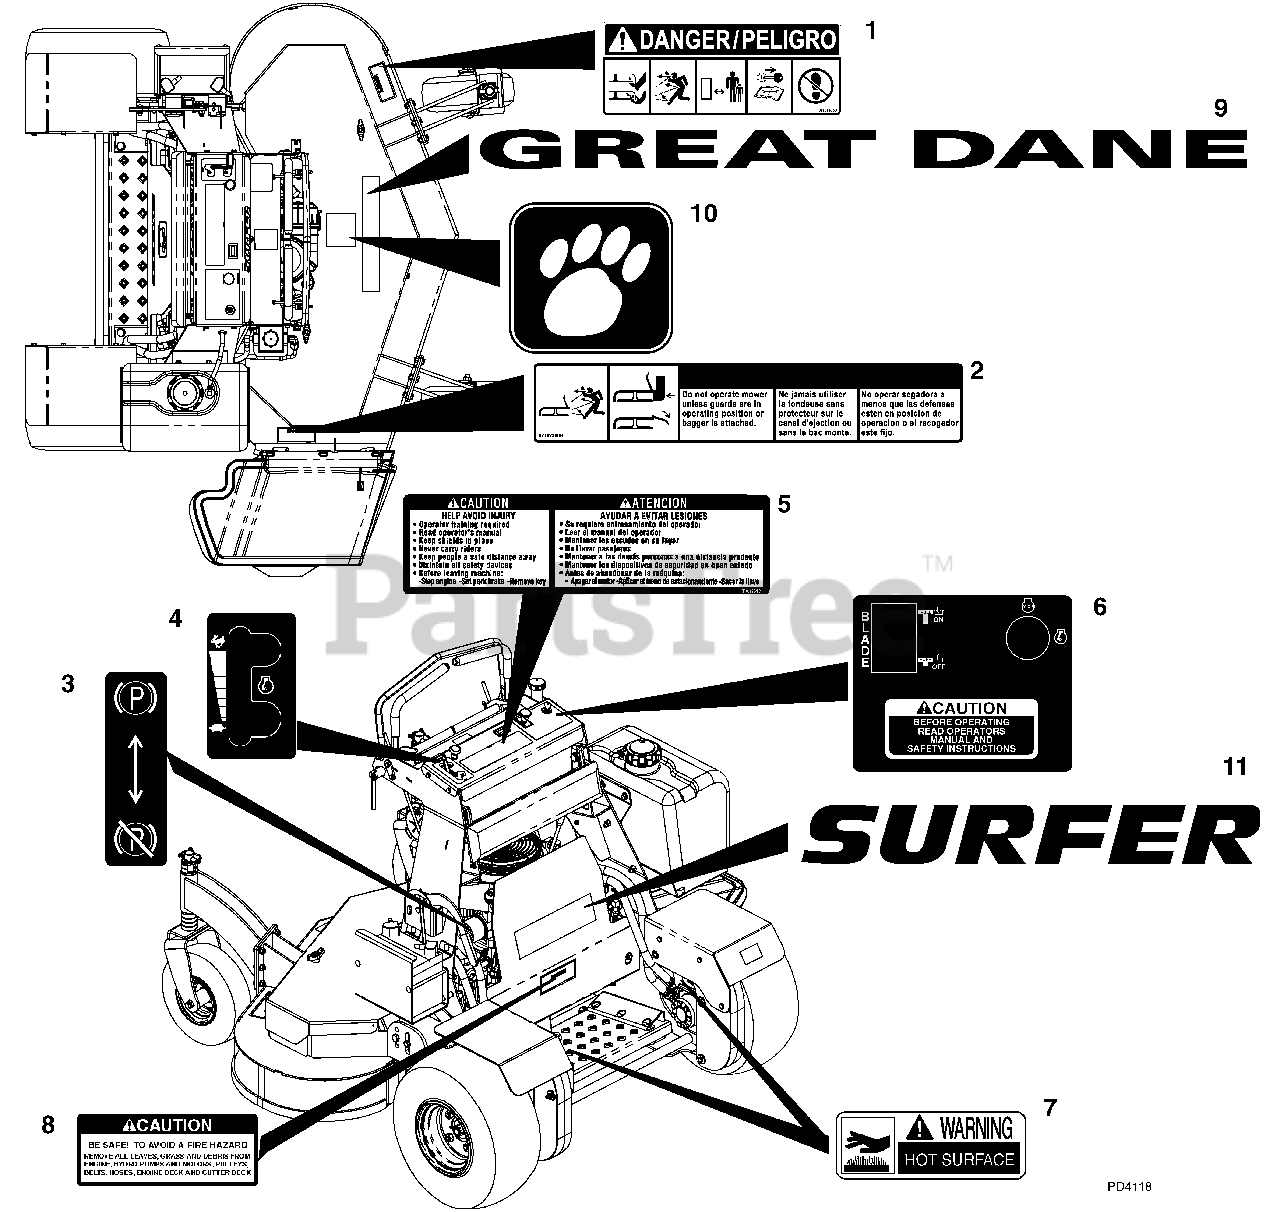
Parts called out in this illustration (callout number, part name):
1	Decal, Danger - Blade Contact
2	Decal, Danger - Rotating Blades
3	Decal, Park Brake
4	Decal, Throttle
5	Decal, General Caution
6	Decal, PTO/Ignition
7	Decal, Warning, Hot Surface
8	Decal, Fire Hazard
9	Decal, Great Dane
10	Decal, Paw Print
11	Decal, Surfer 10.5"
